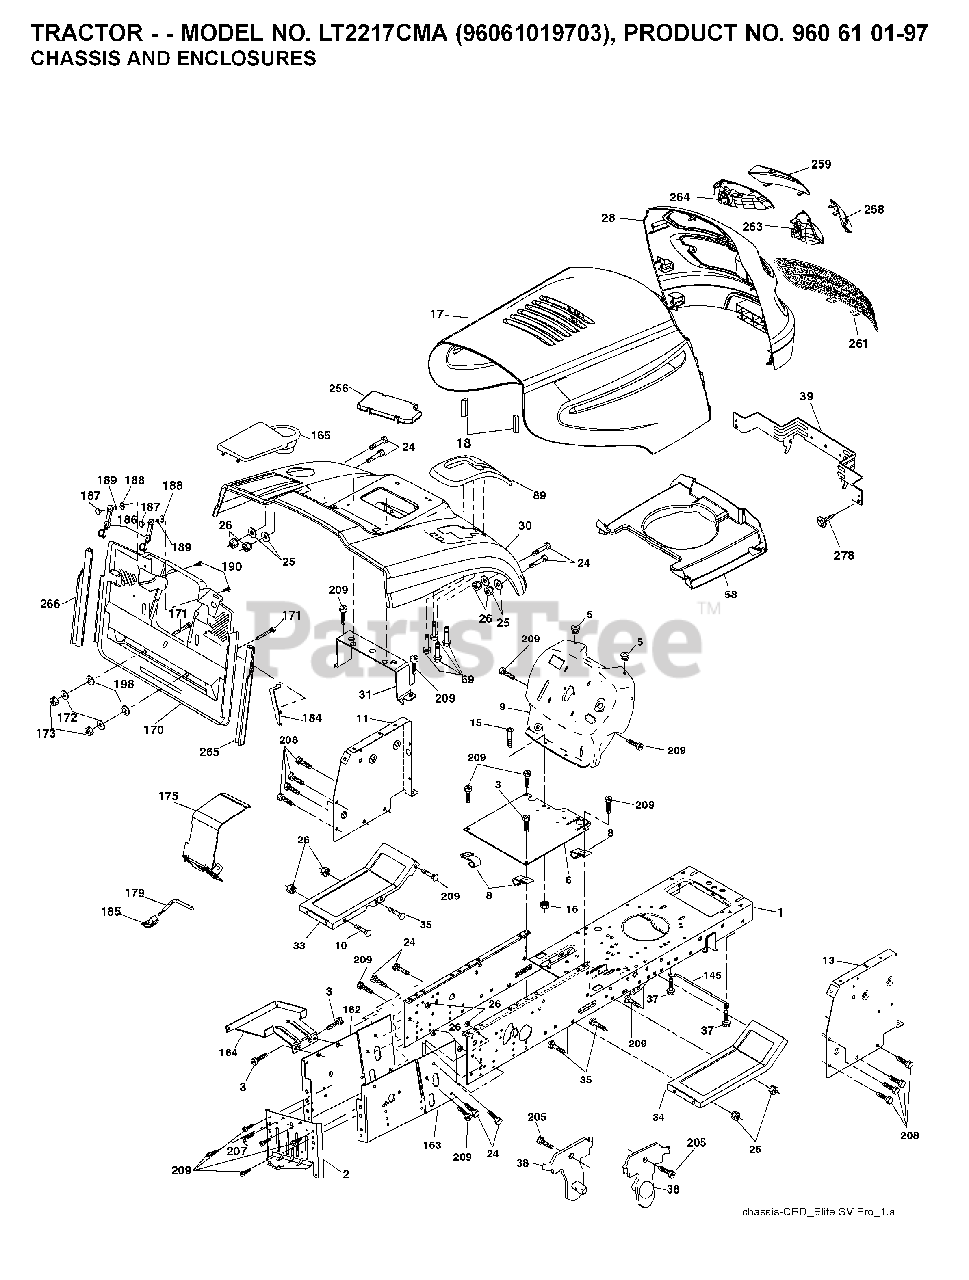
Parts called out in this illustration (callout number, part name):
1	CHASSIS
3	SCREW 3/8-16X3/4
5	BUMPER.RUBBER.HOOD
8	CLIP,INSULATOR
10	BOLT D
11	PANEL.DASH.LH.LTX
13	PANEL DASH RH
16	NUT
18	BUMPER.HOOD.LARGE.1.75"
24	BOLT
25	WASHER
26	NUT
31	BRACKET SUPPORT FENDER
35	BOLT
37	SCREW LT
39	BRACKET PIVOT
69	SCREW.HI-LO.CONSOLE
145	ROD.PIVOT.HOOD
164	SUPPORT
171	BOLT
172	WASHER
186	LATCH ASSY
187	WELDNUT
189	LOCKWASHER
190	SCREW
205	SCREW LT
207	SCREW, 5/16-18 X 1/2
208	SCREW 3/8-16X1/2
209	SCREW, 3/8-16X3/4
263	BEZEL GRILL RH
264	BEZEL GRILL LH
278	SCREW
